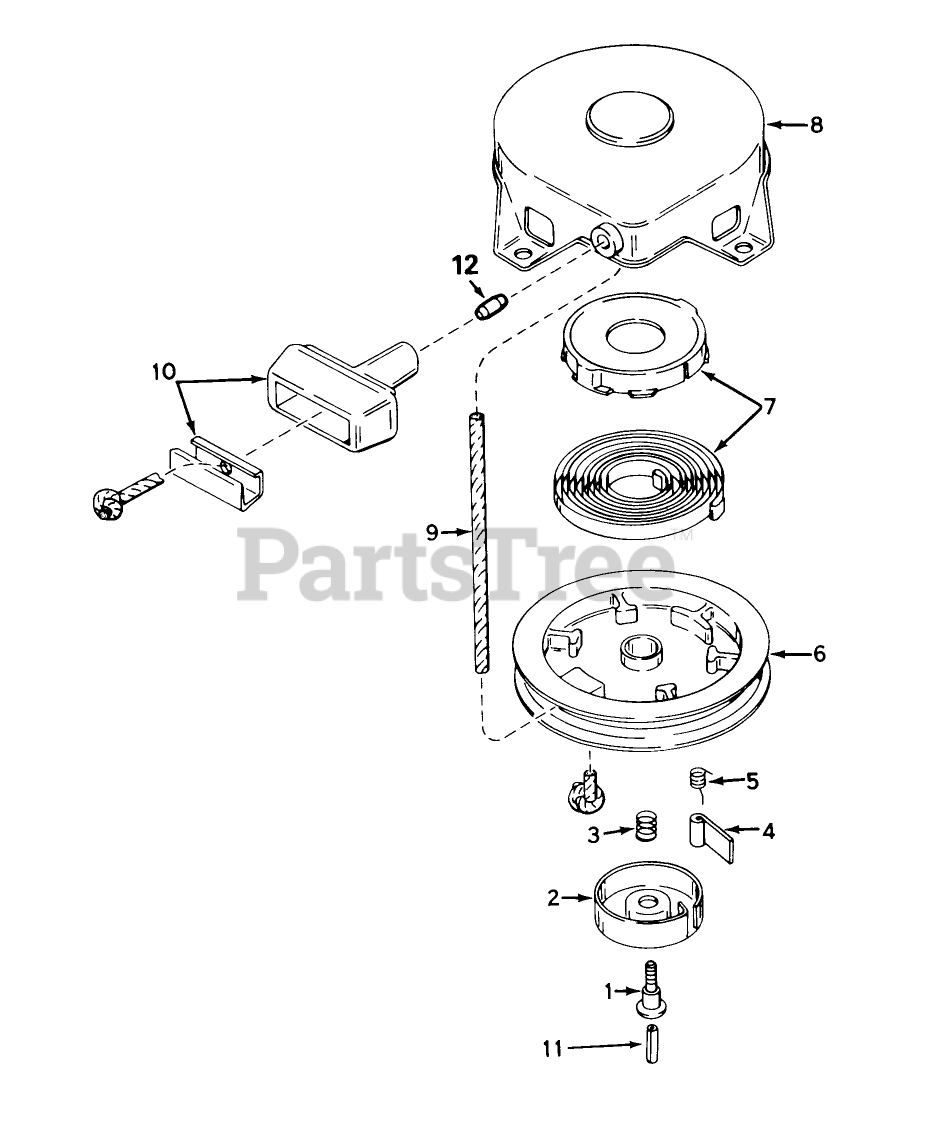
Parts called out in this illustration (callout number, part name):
1	Screw
2	Retainer
3	Spring-Brake
4	Dog-Starter
5	Spring-Dog
6	Pulley
7	Spring Keeper Assy
8	Housing Assy., Starter (Incl. Ref. #1)
9	Rope-Starter (98 cut to length)
10	Assy., Starter
11	Centering
12	Retainer-Starter Rope
